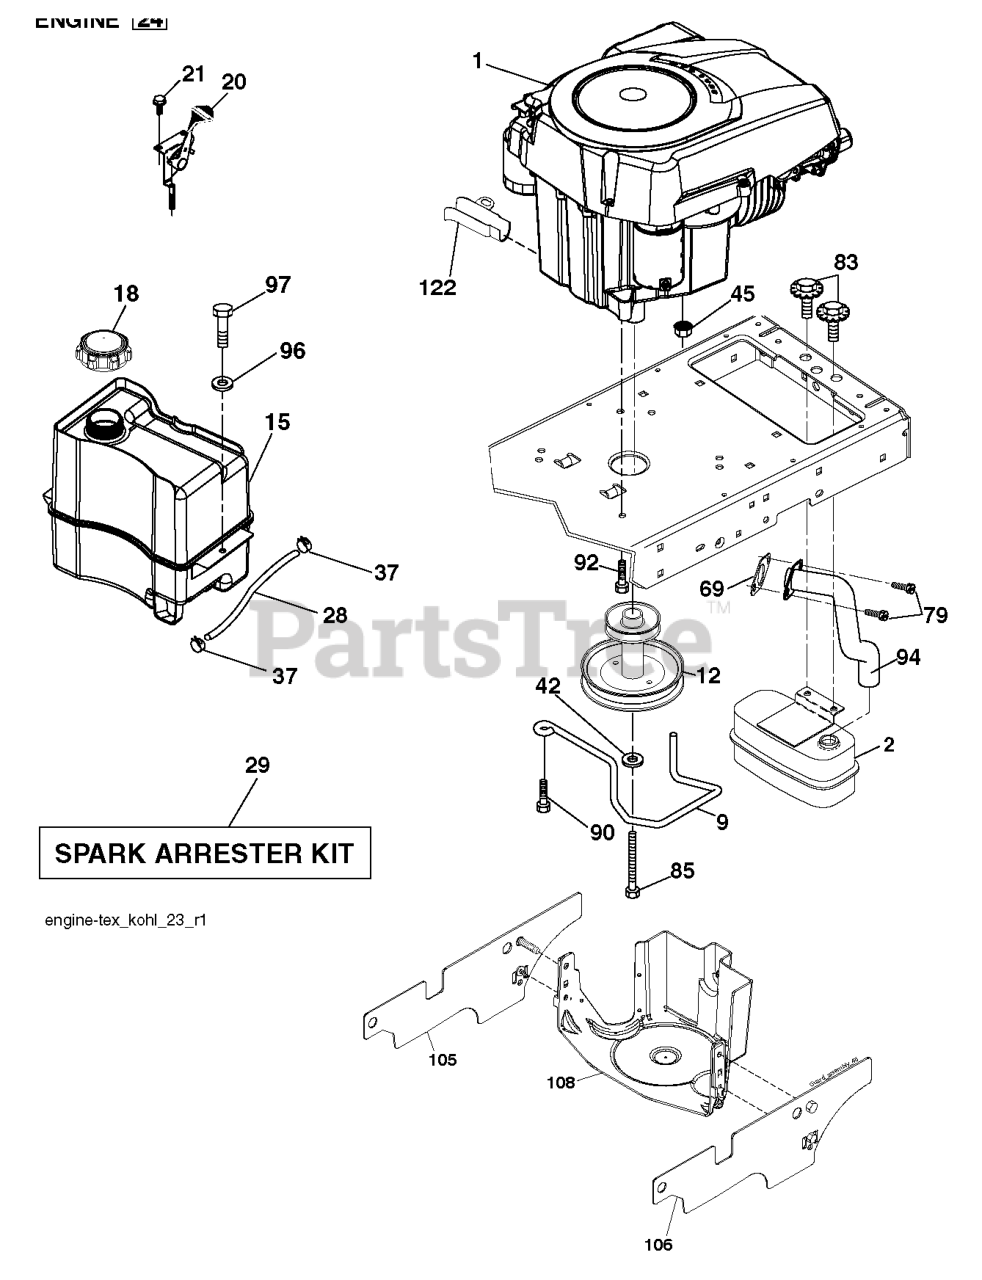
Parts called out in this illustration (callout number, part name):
2	MUFFLER.SINGLE.CYL.KOHL/B&S
9	KEEPER.BELT.ENGINE.4.2
12	PULLY ENGINE
15	RP TANK FUEL FRT 1.5 GAL
18	CAP ASM.FUEL.2.25"FR.
20	CONTROL.TH/CK.C.
21	SCREW.#10 X 0.750.BOS
28	LINE.FUEL.20
29	KIT.SPARK ARRESTOR 794945 B&S
37	HOSE CLAMP
42	LOCKWASHER
45	NUT
69	GASKET.EXHAUST.KOHLER
79	SCREW.SOCKET HD.5/16-1
83	BOLT.5/16-18UNCX3/4 W/SEMS.BLK
85	BOLT HEX 7/16-20X4-1/4"
90	SCREW 3/8-16X1
92	SCREW 3/8-16X1
94	RP.TUBE.EXHAUST.KOHL.COURAGE
97	SCREW HEXWSHR 1/4-20X3/4
108	ENGINE COVER
122	EXTENSION DRAIN OIL
